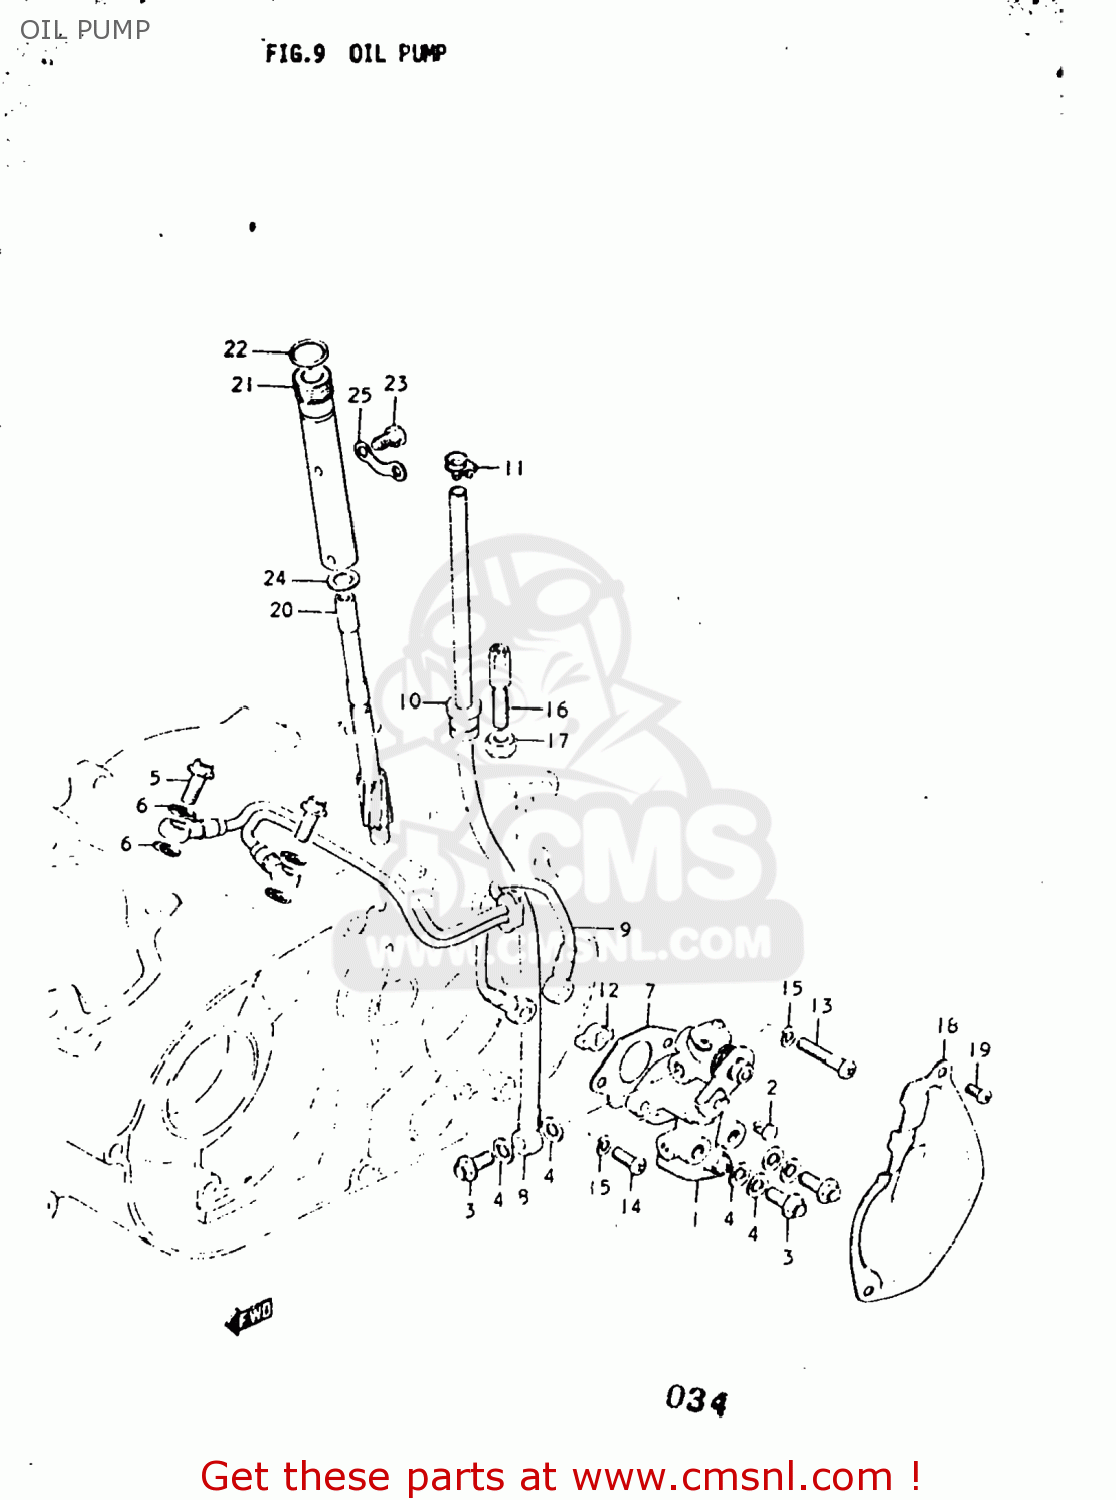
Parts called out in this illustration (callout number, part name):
1	PUMP ASSEMBLY,OIL
2	TERMINAL,CABLE
3	UNION BOLT
4	GASKET (NAS)
5	UNION BOLT
6	GASKET
7	GASKET,OIL PUMP (MCA)
8	HOSE,OIL NO.1
9	HOSE,OIL NO.2
10	BUSHING
11	CLAMP
12	PIECE,OIL PUMP DRIVE
13	SCREW
14	SCREW
15	LOCK WASHER
16	BOLT
17	NUT
18	CAP
19	SCREW
20	GEAR,TACHOMETER DRIVEN
21	SLEEVE,TACHOMETER DRIVE
22	O RING(D:1.3,ID:9.6)
23	BOLT(6X12)
24	WASHER(8X13.7X1)
25	CLAMP
